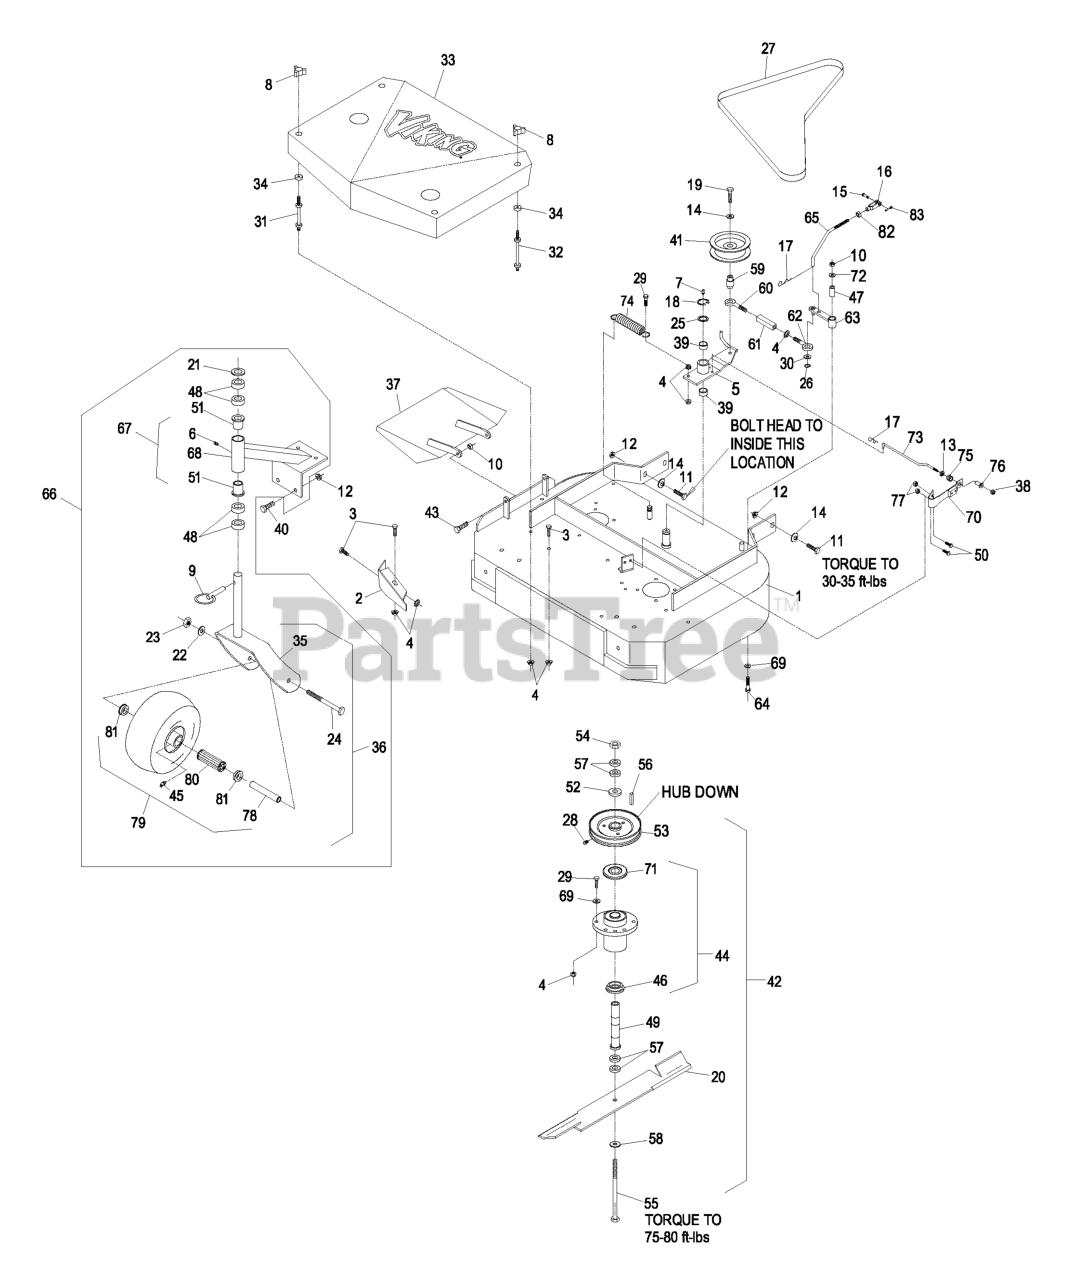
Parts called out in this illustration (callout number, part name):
1	ASM,DECK 36 RIGID
2	BAFFLE-DOGLEG
3	SCREW-HH
5	IDLER ARM ASM
6	FITTING-GREASE
7	FITTING-GREASE
8	KNOB-3 PRONG
10	NUT-LOCK, NI
11	SCREW-HH
12	NUT-HHF, WHIZ
13	RING-PUSH ON
14	WASHER-BELLEVILLE
15	PIN-CLEVIS
16	YOKE-ADJUSTABLE
17	PIN-COTTER
18	RING-RETAINING, EXT
19	SCREW-HH
21	WASHER-FLAT
22	WASHER-LOCK
23	NUT-HH
24	SCREW-HH
25	WASHER-SPINDLE
26	RING-RETAINING, EXT
27	BELT,BLADE VIKING HYD 36
28	SCREW-SET
29	SCREW-HH
30	WASHER-PLAIN
31	STUD-SHIELD, BELT (SHORT)
32	STUD-SHIELD, BELT (LONG)
33	STUD-SHIELD, BELT (LONG)
36	ASM,CASTER/WHEEL
37	WLD,CHUTE 36 RIGID
38	NUT-LOCK, NI
39	SLEEVE-BEARING
40	SCREW-HH
42	ASM, CUTTER HOUSING OUTER
43	SCREW-HH
44	KIT, CUTTER HOUSING
45	FITTING-GREASE
46	SPACER-GUARD, BOTTOM
47	TUBE-PIVOT
48	SPACER-CASTER
49	TUBE-SPINDLE, SHORT
50	SCREW-HH
51	BEARING-FLANGED
52	WASHER-RETAINER, SHEAVE
53	SHEAVE
54	NUT-HEX
55	SCREW-CAP, HH
58	WASHER-SPRING
59	BUSHING-ENGAGEMENT
60	EYEBOLT-THREAD, LH
61	BODY-TURNBUCKLE
62	EYEBOLT-THREAD, RH
63	ARM-ASSIST, 32/36
64	SCREW-HH
65	ARM-LINKAGE, ASSIST
67	ASM,CSTR SUPPORT W/WEIGHT
69	WASHER-SPRING
70	PAD AND SPRING ASM
71	GUARD-BEARING, TOP
72	WASHER-FLAT
73	ROD-BRAKE
74	SPRING-EXTENSION
75	SPRING-COMPRESSION
76	SPACER-FLANGED
77	NUT-LOCK, NI
79	KIT, SP CASTER WHEEL REPL
80	BEARING
81	BUSHING
82	NUT-HEX
83	PIN-COTTER
